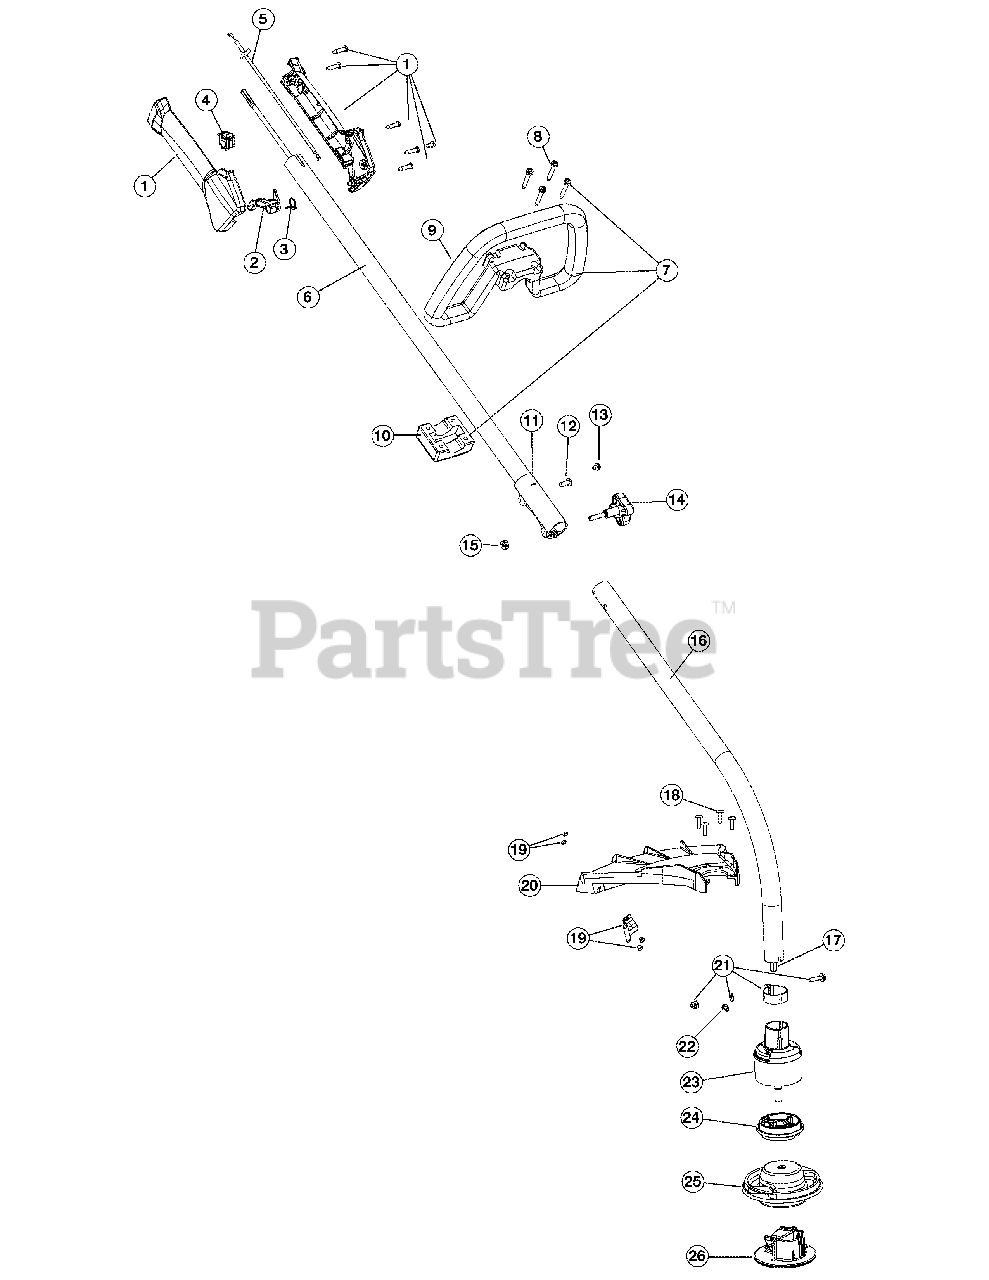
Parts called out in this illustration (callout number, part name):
1	Throttle Housing Assembly
2	Throttle Trigger
3	Throttle Trigger Spring
4	Switch Assembly
5	Throttle Cable Assembly
6	Upper Drive Shaft Housing
7	Deluxe D-Handle Assembly
9	D-Handle
10	D-Handle Base
11	Click Link Coupler
14	Adjustment Knob
15	Nut
16	Lower Drive Shaft Housing
17	Lower Flexible Drive Shaft
18	Shield Mount Hardware
19	Blade Assembly
20	Shield Assembly
21	Lower Clamp Assembly
22	Anti-Rotation Screw
23	Bushing Housing Assembly
24	Adapter
25	Cutting Head Assembly
26	Cutting Head Cap
